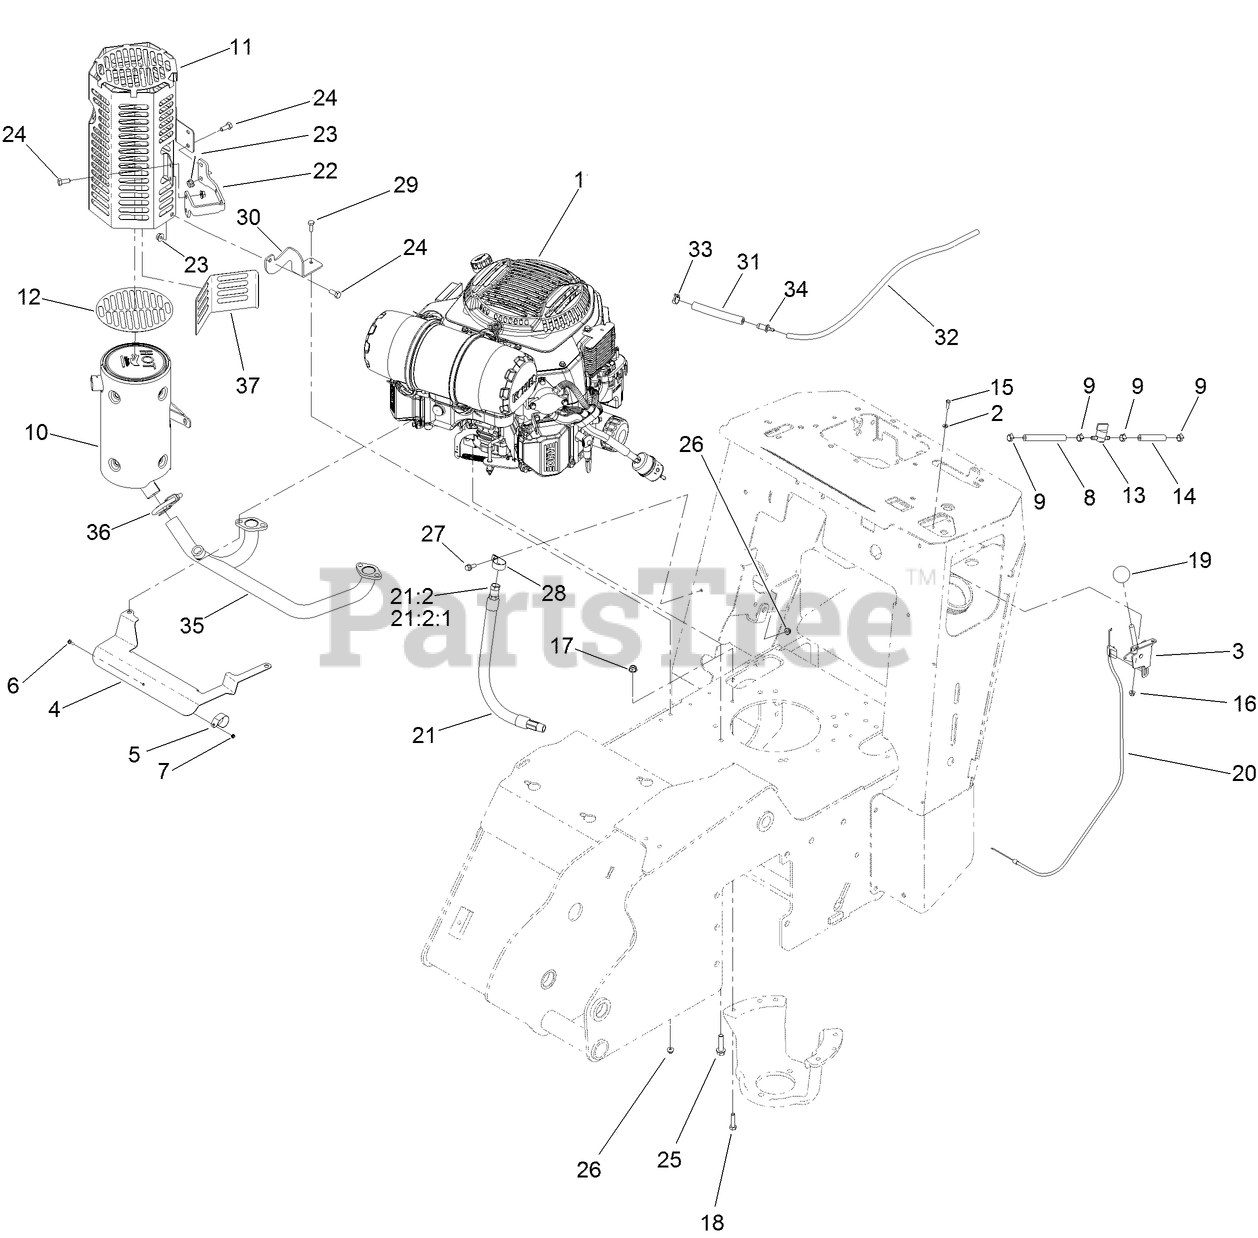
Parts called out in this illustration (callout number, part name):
1	ENGINE-KOHLER, PS-ECV749-3068
2	WASHER-FLAT
3	LEVER-CONTROL
4	SHIELD-HEAT
6	SCREW-PAN
7	NUT-HEX
8	HOSE-FUEL
9	CLAMP-HOSE
10	MUFFLER-KOHLER
11	GUARD-MUFFLER
12	FOIL-GUARD
13	VALVE-FUEL
14	HOSE-FUEL
16	NUT-HF
17	NUT-HF, NI
18	SCREW-HH
20	CABLE-CONTROL
21	OIL DRAIN HOSE ASM
21:2	PLUG-HH
21:2:1	O-RING
22	BRACKET-MUFFLER
23	NUT-FLANGE
24	SCREW-HH
25	SCREW-HWH
26	NUT-HF
27	SCREW-HHF
28	CLAMP-R
29	SCREW-HH
30	BRACKET-GUARD, MUFFLER
31	HOSE-VENT
32	HOSE-VENT
33	CLAMP-HOSE
34	FITTING-ORIFICE, STRAIGHT
35	MANIFOLD-KOHLER
36	CLAMP-MUFFLER
37	GUARD-FOIL
